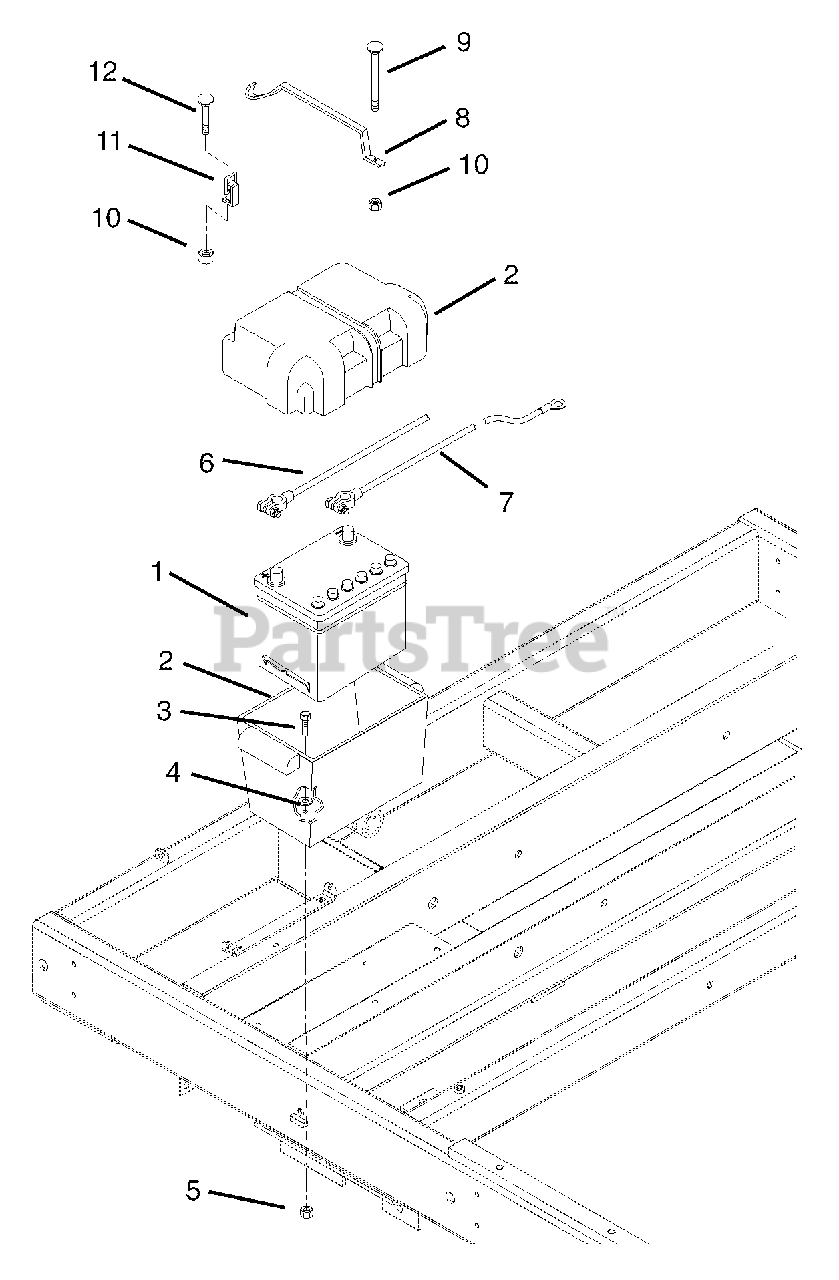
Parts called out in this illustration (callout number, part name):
2	Battery Box
3	Bolt-Hex .25-20 x .75 Grade 5
4	Washer-Flat-Steel .312 x .734 x .065
5	Nut-Locking-Center .25-20
6	Battery Cable
6	Cable-Battery Positive
7	Cable-Negative Battery
8	Strap-Battery Hold Down
9	Bolt-Round Head Square Neck .31-18 x 6.50
10	Nut-Locking-Center .31-18
11	Latch Assembly-Battery Hold Down
12	Bolt-Round Head Square Neck .31-18 x 2.50
